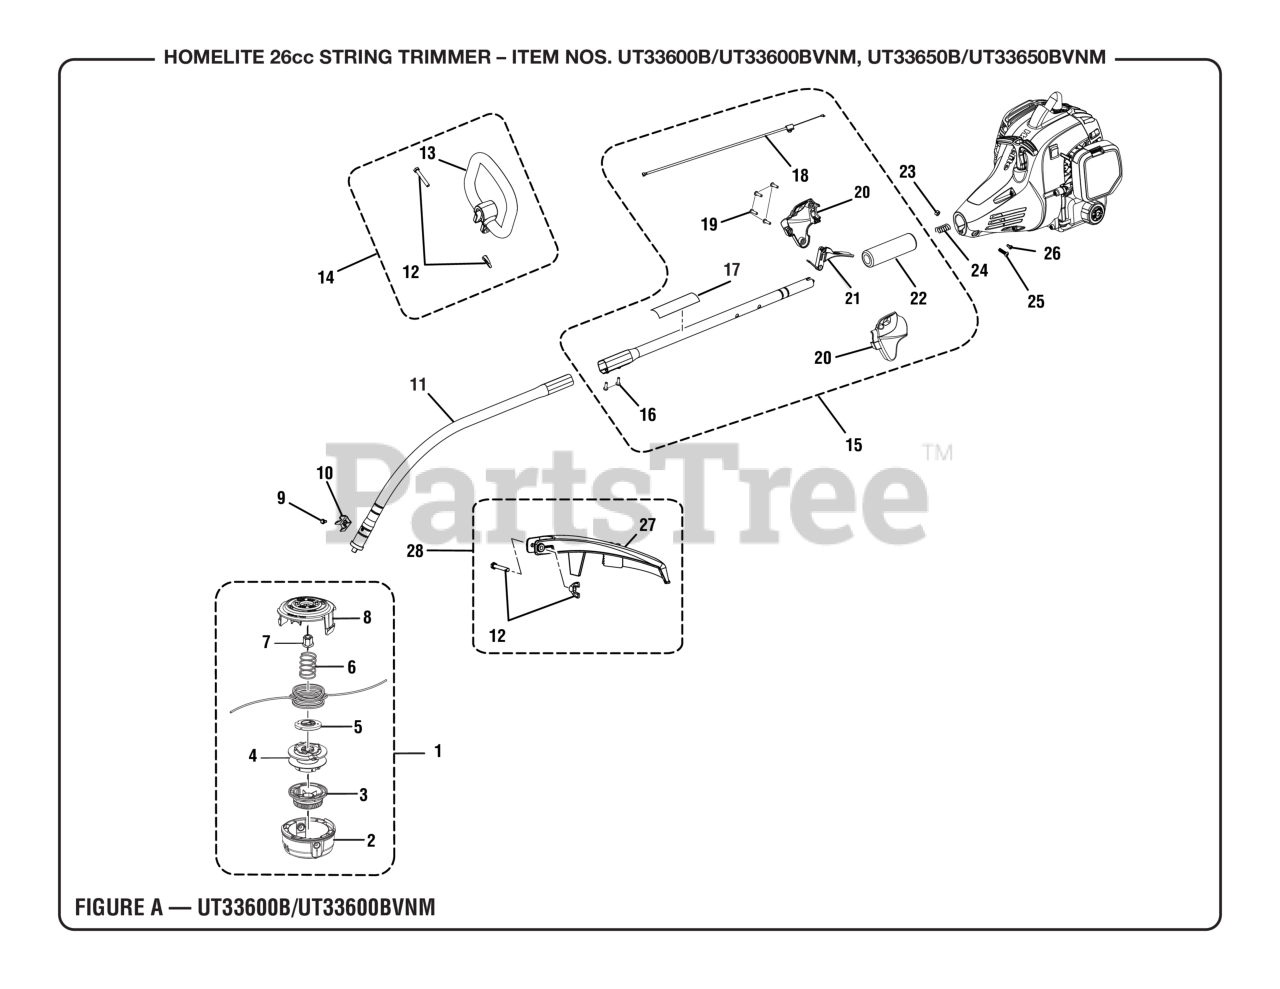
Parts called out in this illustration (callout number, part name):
1	Trimmer Head Assembly
2	Lower Housing
3	Bump Knob (Gray)
4	Spool Assembly
5	String Guide
6	Compression Spring
7	Flange Nut (M8)
8	Upper Housing
9	Screw (#10-32 x 3/8 in., Hex Washer Hd. S.T.)
11	Lower Boom Assembly
12	Fastener Parts Kit
13	Front Handle
14	Front Handle Assembly
15	Boom Assembly
16	Set Screw (M5 x 10 mm, Hex Soc. Hd.)
17	Icon Warning Label
18	Throttle Cable
19	Screw (M4 x 20 mm, T20 Torx Pan Hd. T.Fl.)
20	Trigger Handle Assembly
21	Throttle Trigger
22	Rubber Grip
23	Hex Nut (M6.3 x 1)
24	Compression Spring
25	Screw (M6 x 20 mm, T27 Torx Button Hd.)
26	Screw (M4 x 8 mm, T25 Torx Pan Hd. T.F.)
27	Grass Deflector
28	Grass Deflector Assembly
